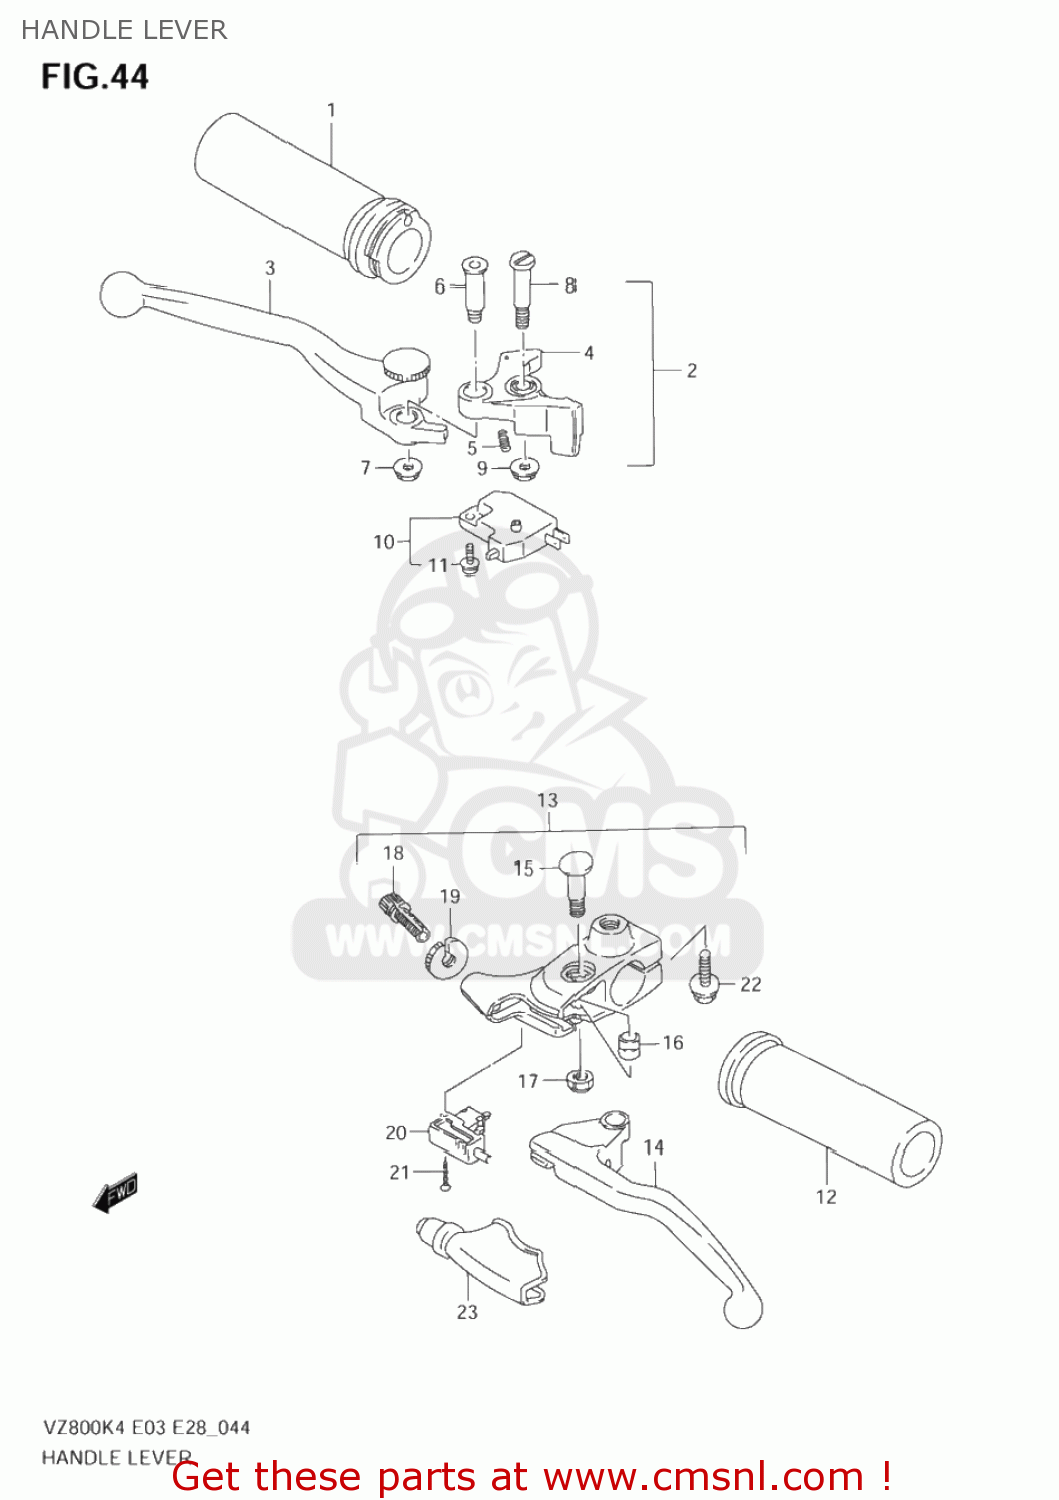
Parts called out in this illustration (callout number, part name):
1	GRIP,THROTTLE
2	LEVER ASSY,BRAKE
3	LEVER,ADJUST
4	KNOCKER
5	SPRING
6	BOLT,LEVER
7	NUT
8	BOLT,LEVER PIVOT
9	NUT
10	SWITCH ASSY,ST
11	SCREW
12	GRIP,L
13	LEVER ASSY,CLUTCH
14	LEVER,CLUTCH
15	BOLT,CLUTCH LEVER
16	SPACER,CLUTCH LEVER PIVOT
17	NUT 6MM
18	ADJUSTER,WIRE
19	NUT,LOCK
20	SWITCH,CLUTCH
21	SCREW
22	BOLT
23	COVER,CLUTCH LEVER
